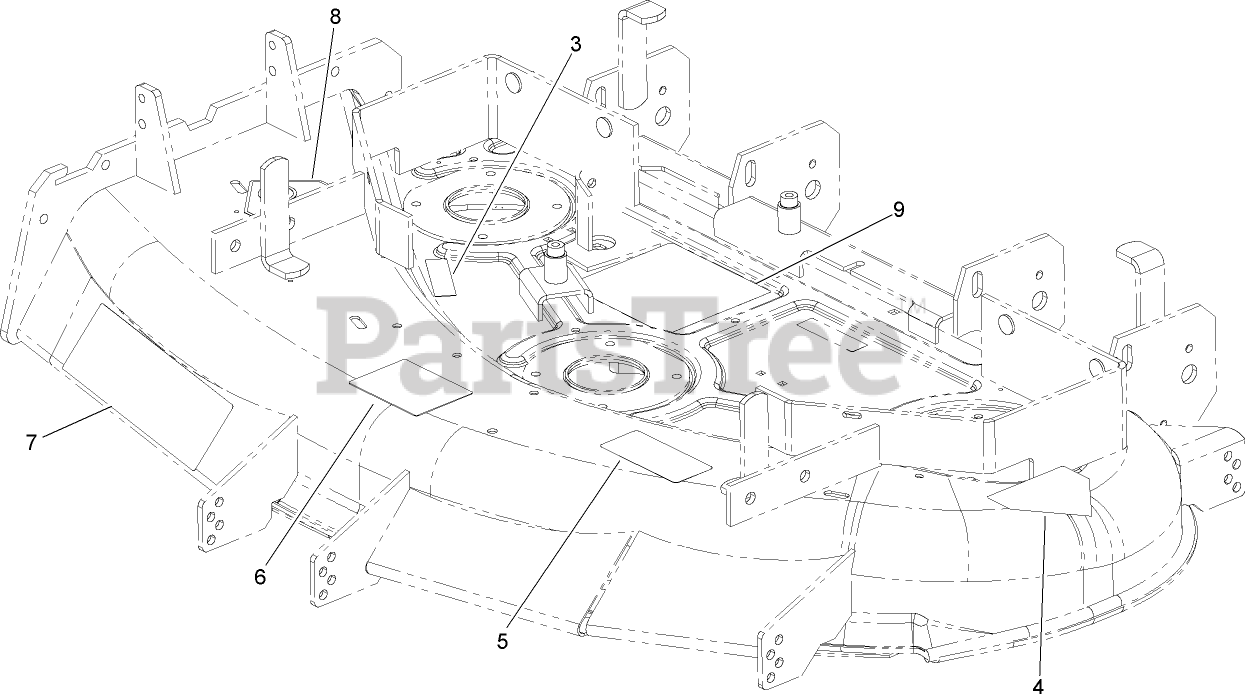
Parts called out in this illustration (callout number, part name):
3	DECAL-COVER, MISSING
4	DECAL-DANGER
5	DECAL-TORQUE
6	DECAL-WHEEL, GAGE
8	DECAL-DANGER
9	DECAL-SERVICE AID, BELT ROUTING
